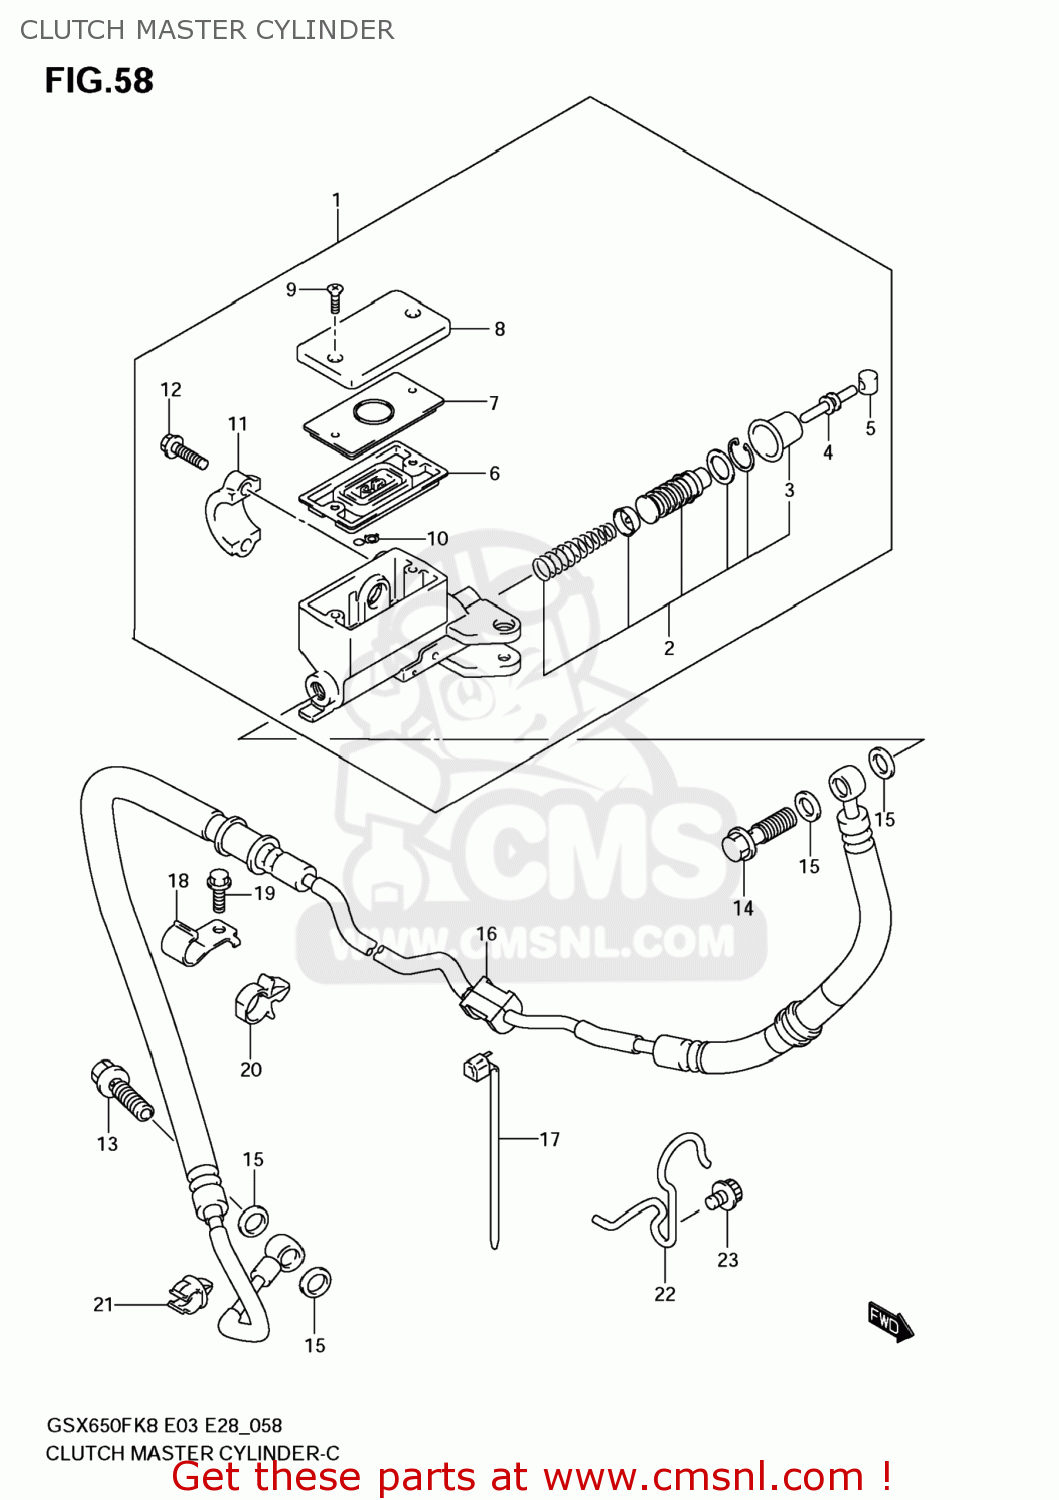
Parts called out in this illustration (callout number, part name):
1	CYLINDER ASSY,
2	PISTON & CUP SET
3	BOOT
4	PUSH ROD
5	BUSH
6	7
7	PLATE,DIAPHRAGM
8	CAP
9	SCREW
10	PROTECTOR
11	HOLDER
12	BOLT(6X22)
13	BOLT UNION
14	BOLT UNION
15	WASHER(10X15X1.5)
16	HOSE,CLUTCH
17	CLAMP(L:95)
18	CLAMP,CLUTCH HOSE NO.2
19	BOLT
20	CLAMP
21	CLAMP
22	CLAMP,CLUTCH HOSE NO.3
23	BOLT
